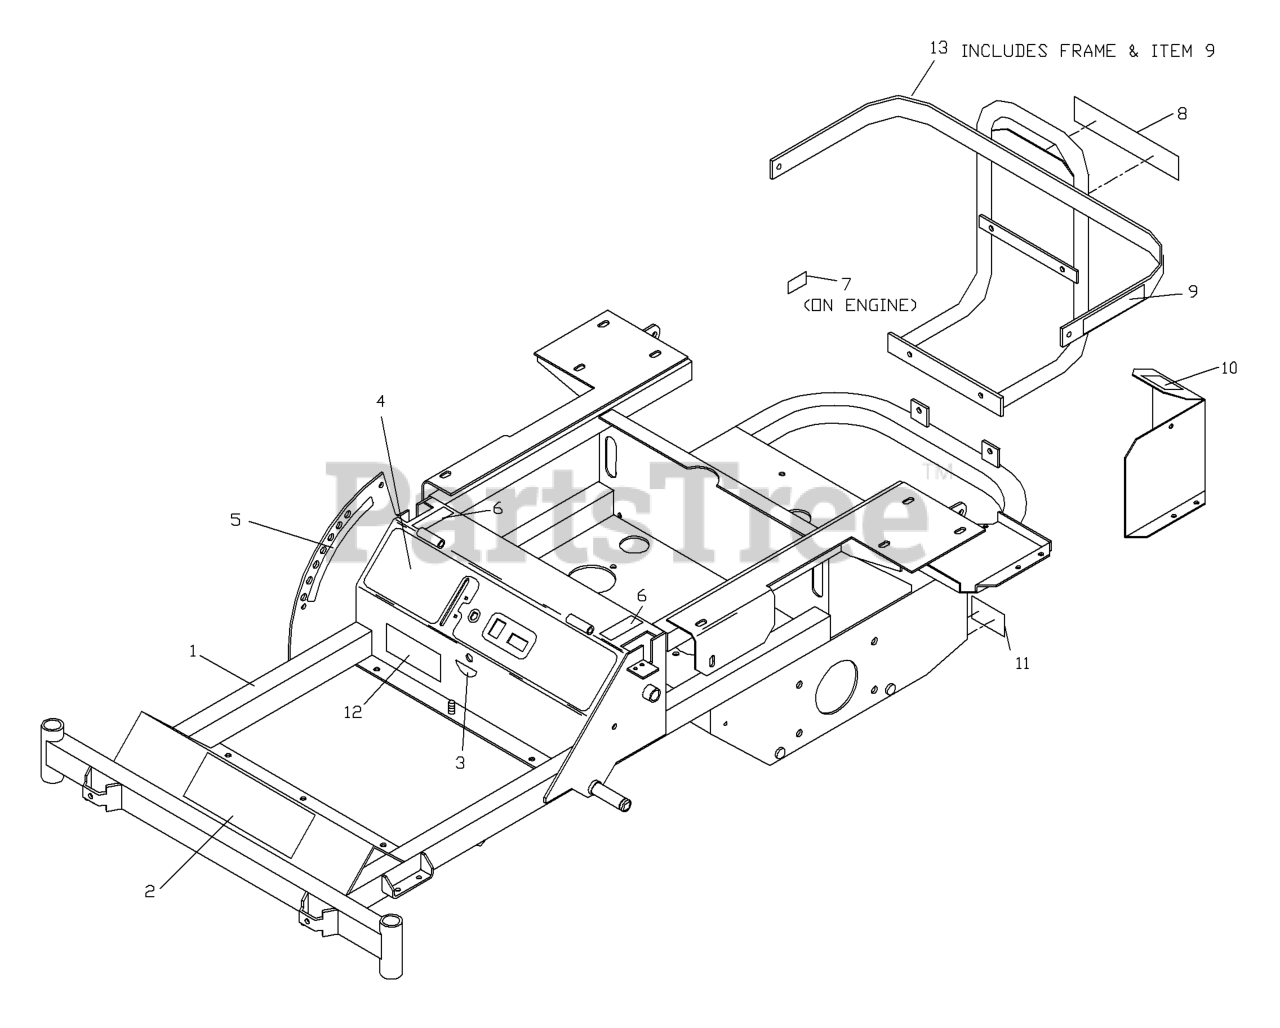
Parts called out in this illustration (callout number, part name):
1	FRAME W/DECALS KOHLER
1	FRAME W/DECALS KAWASAKI
2	DECAL, HUSQVARNA 15.5"
3	DECAL, FUEL VALVE
4	CONSOLE DECAL
4	DECAL, CONSOLE KOHLE
5	DECAL, LOCATOR
6	DECAL, MOTION CONTROL
7	DECAL, EXHAUST
8	DECAL, HUSQVARNA LOGO 9.25"
9	DECAL, BATTERY
10	DECAL, PROP. 65
11	DECAL, DANGER
12	DECAL, NASCAR
13	ENGINE GUARD W/DECAL
